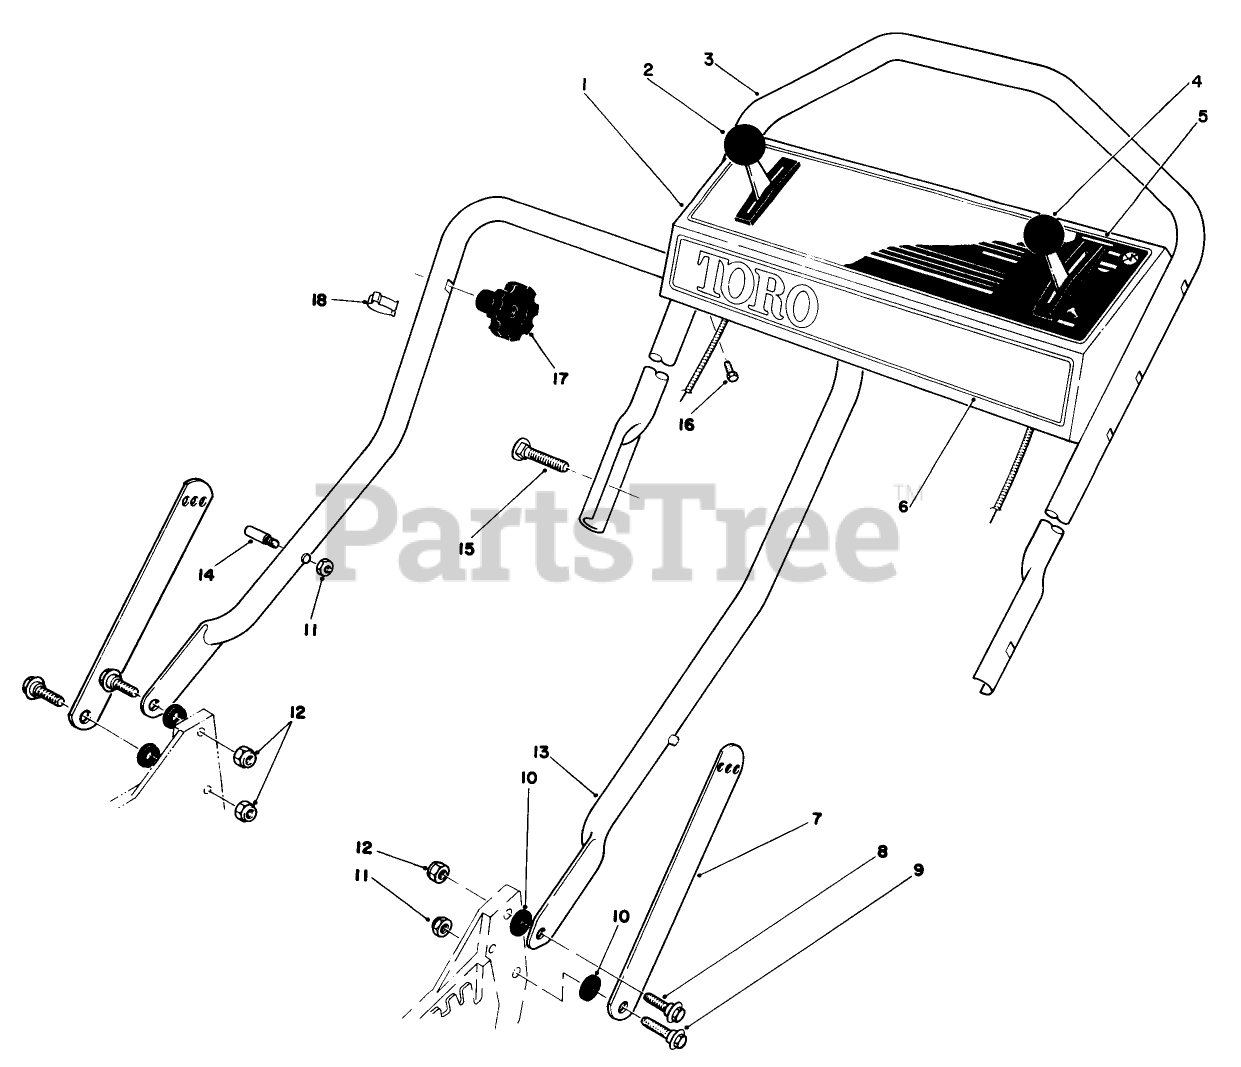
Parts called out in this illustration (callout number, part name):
2	GROUND SPEED CONTROL
4	SERVICE THROTTLE CONTRO
8	SCREW-SHOULDER
9	SCREW-SHOULDER
10	SPACER
11	NUT-LOCK, NI
12	NUT-LOCK, NI
14	HANDLE PIN
16	SCREW-HWHTF
18	BOWDEN CLIP
